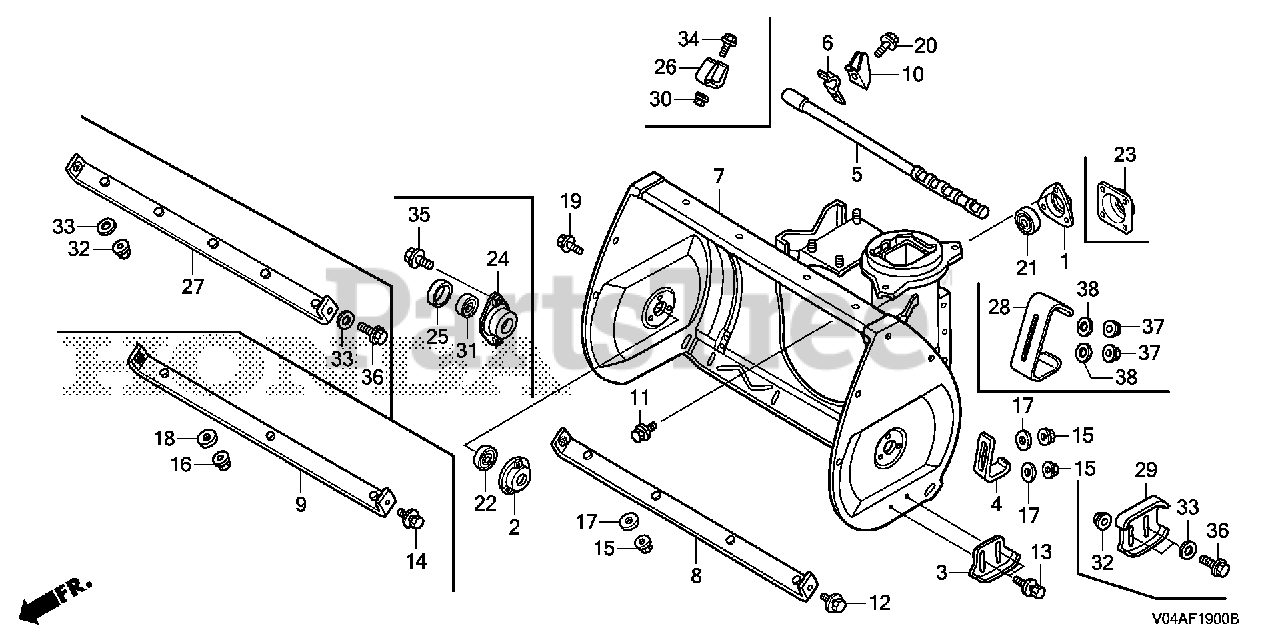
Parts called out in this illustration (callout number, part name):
5	BAR, SNOW DROP
7	HOUSING, AUGER *R280* (POWER RED)
11	BOLT, FLANGE (8X12)
21	BEARING, RADIAL BALL (6205UU)
23	HOLDER, BLOWER SHAFT BEARING
24	HOLDER, AUGER BEARING
25	SPACER, AUGER BEARING
26	BRACKET, SNOW DROP BAR
27	BLADE, SCRAPER
28	SKID, AUGER
30	NUT, NYLON RING (6MM)
30	NUT, SELF-LOCK (6MM)
31	BEARING, RADIAL BALL (6203-19.05)
32	NUT, FLANGE (8MM)
33	WASHER, PLAIN (8MM)
34	BOLT, FLANGE (6X12)
35	BOLT, FLANGE (8X12)
36	BOLT, FLANGE (8X16)
37	NUT, FLANGE (8MM)
38	WASHER, PLAIN (8MM)
